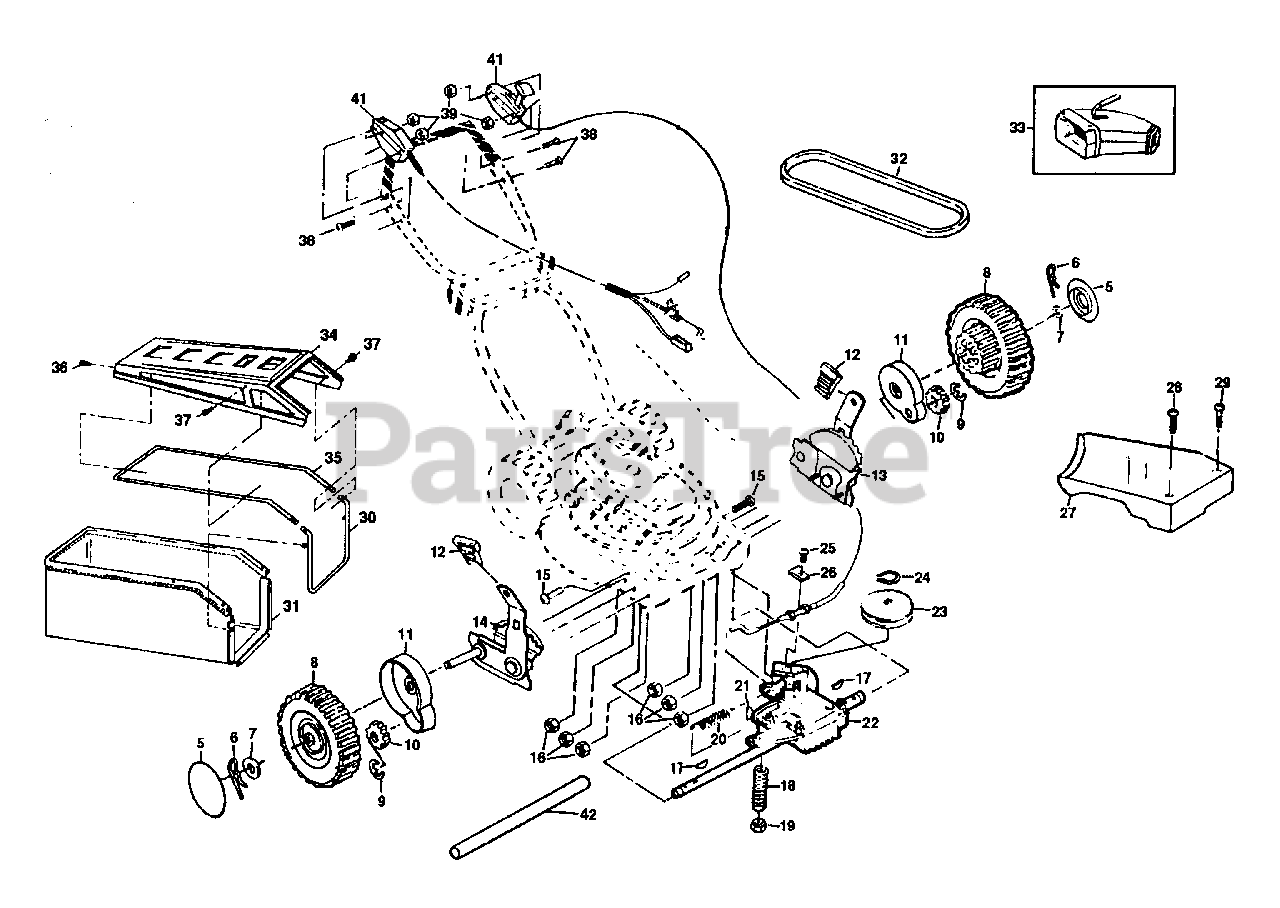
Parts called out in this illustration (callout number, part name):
1	Engine Control (AYP part number)
2	Locknut 1/4-20 (AYP part number)
6	Retainer Clip (AYP part number)
7	Washer (AYP part number)
8	Wheel & Tire Assembly 8.00 x 1-3/4 (AYP part number)
9	E-ring (AYP part number)
10	Pinion (AYP part number)
11	Dust Cover (AYP part number)
12	Selector Knob (AYP part number)
13	Wheel Adjuster Assembly (Left) (AYP part number)
14	Wheel Adjuster Assembly (Right) (AYP part number)
15	Flat Head Machine Screw 1/4-20 x 3/4 (AYP part number)
16	Locknut (AYP part number)
17	Woodruff Key #3 (AYP part number)
18	Spring (AYP part number)
19	Locknut 1/4-20 (AYP part number)
21	Woodruff Key #213 (AYP part number)
22	Gear Case Assembly (AYP part number)
23	Drive Pulley (AYP part number)
24	Retaining Ring (AYP part number)
25	Pan Head Self-tapping Screw #10-24 (AYP part number)
26	Cable Clamp (AYP part number)
27	Drive Cover (AYP part number)
28	Pan Head Machine Screw #10-24 x 2-3/4 (AYP part number)
29	Pan Head Machine Screw #10-24 x 1-3/4 (AYP part number)
30	Catcher Frame (AYP part number)
31	Grass Catcher
34	Catcher Top (AYP part number)
35	Tube Catcher (AYP part number)
36	Screw Self-Tapping #10-24 x .625 (AYP part number)
37	Screw Tapping #10-24 x .38 (AYP part number)
38	Machine Screw 1/4-20 x 2-1/2 (AYP part number)
39	Locknut 1/4-20 (AYP part number)
41	Drive Control (AYP part number)
42	Drive Shaft, Cover (AYP part number)
